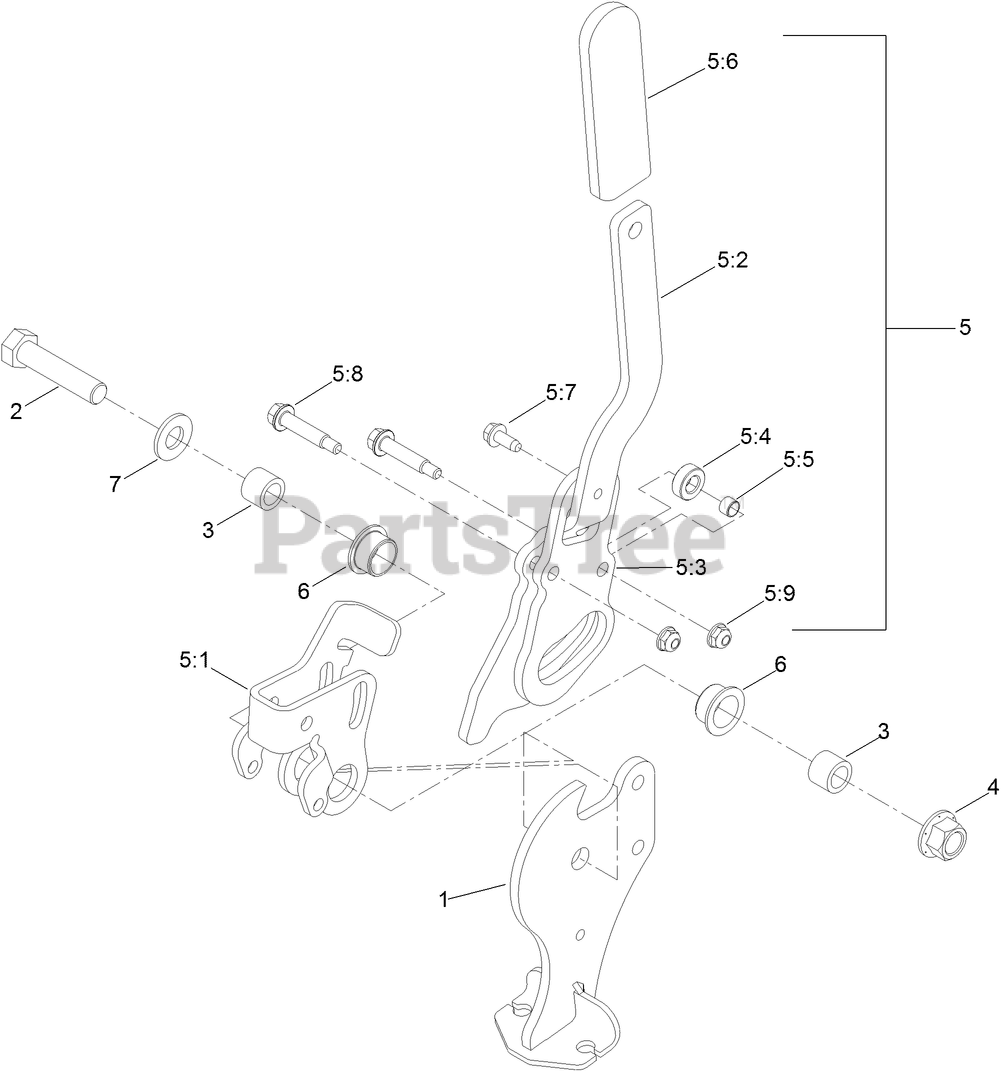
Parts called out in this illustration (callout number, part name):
1	PIVOT-BRAKE
2	SCREW-HH
3	SPACER
4	NUT-LOCK
5	HANDLE ASM
5:1	BELLCRANK-BRAKE
5:2	HANDLE-BRAKE
5:3	PLATE-HANDLE
5:4	ROLLER-BRAKE
5:5	BEARING-SLEEVE
5:6	GRIP-LEVER
5:7	SCREW-HWH
5:8	SCREW-SHOULDER
5:9	NUT-HF
6	BUSHING-FLANGE
7	WASHER-FLAT
